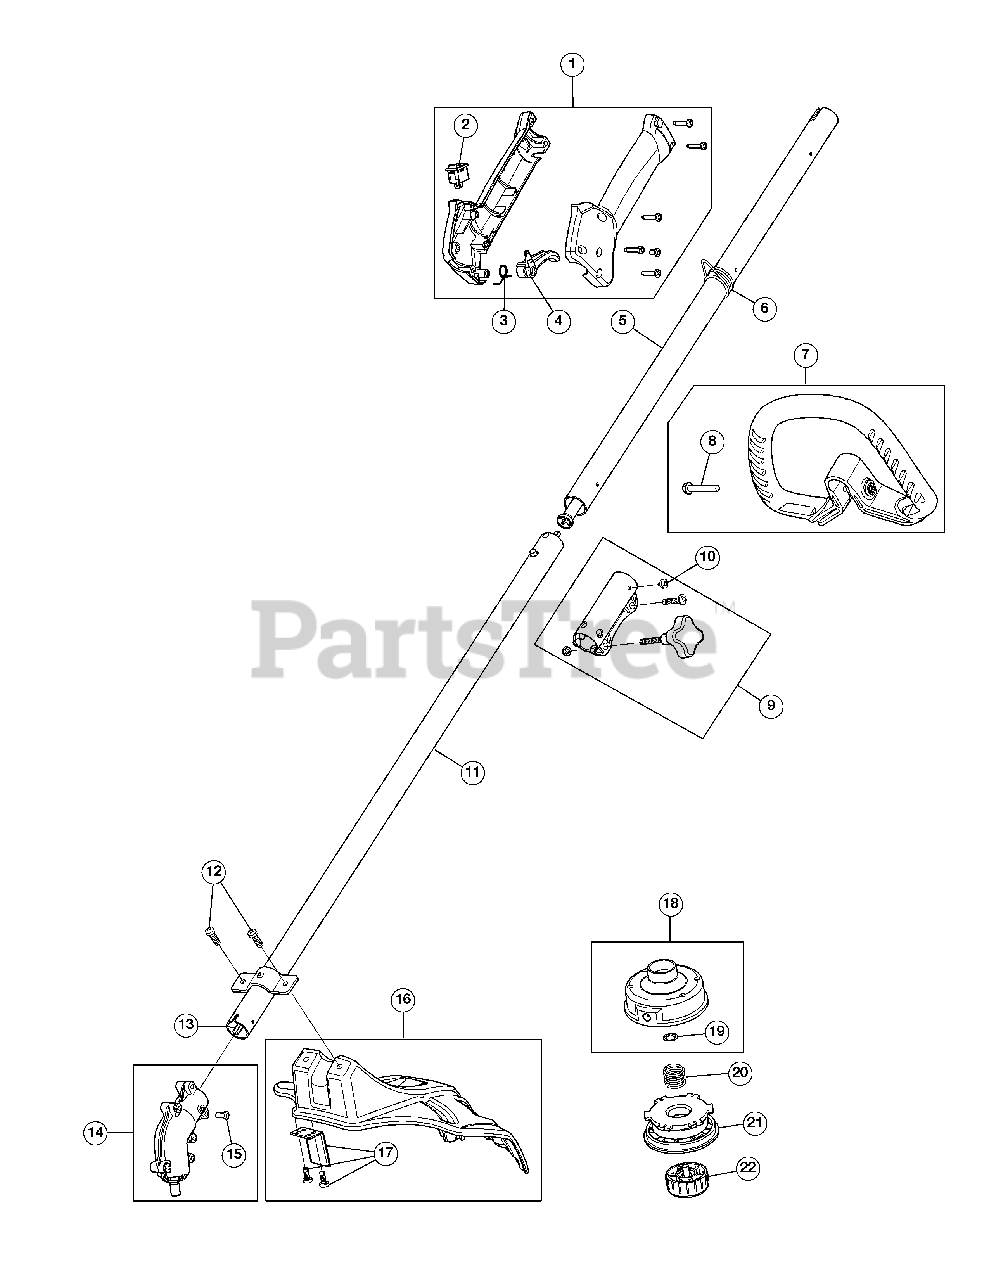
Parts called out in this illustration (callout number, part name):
1	Throttle Housing Assembly (Incl. 2 - 4)
2	Trigger Switch Assembly
3	Throttle Trigger Spring
4	Throttle Trigger
5	Upper Drive Shaft Assembly
6	Shoulder Strap Clip
7	Deluxe D-Handle Assembly (Incl. 8)
9	Split Boom Coupler (Incl. 10)
10	Coupler Anti-Rotation Screw
11	Lower Drive Shaft Assembly
12	Shield Mounting Screws
13	Lower Flexible Drive Shaft
14	Gear Box Assembly (Incl. 15)
15	Anti-Rotation Screw
16	Shield Assembly (Incl. 12 & 17)
17	Blade Assembly
18	Outer Spool Assembly (Incl. 19)
21	Inner Reel
22	Bump Knob Assembly
